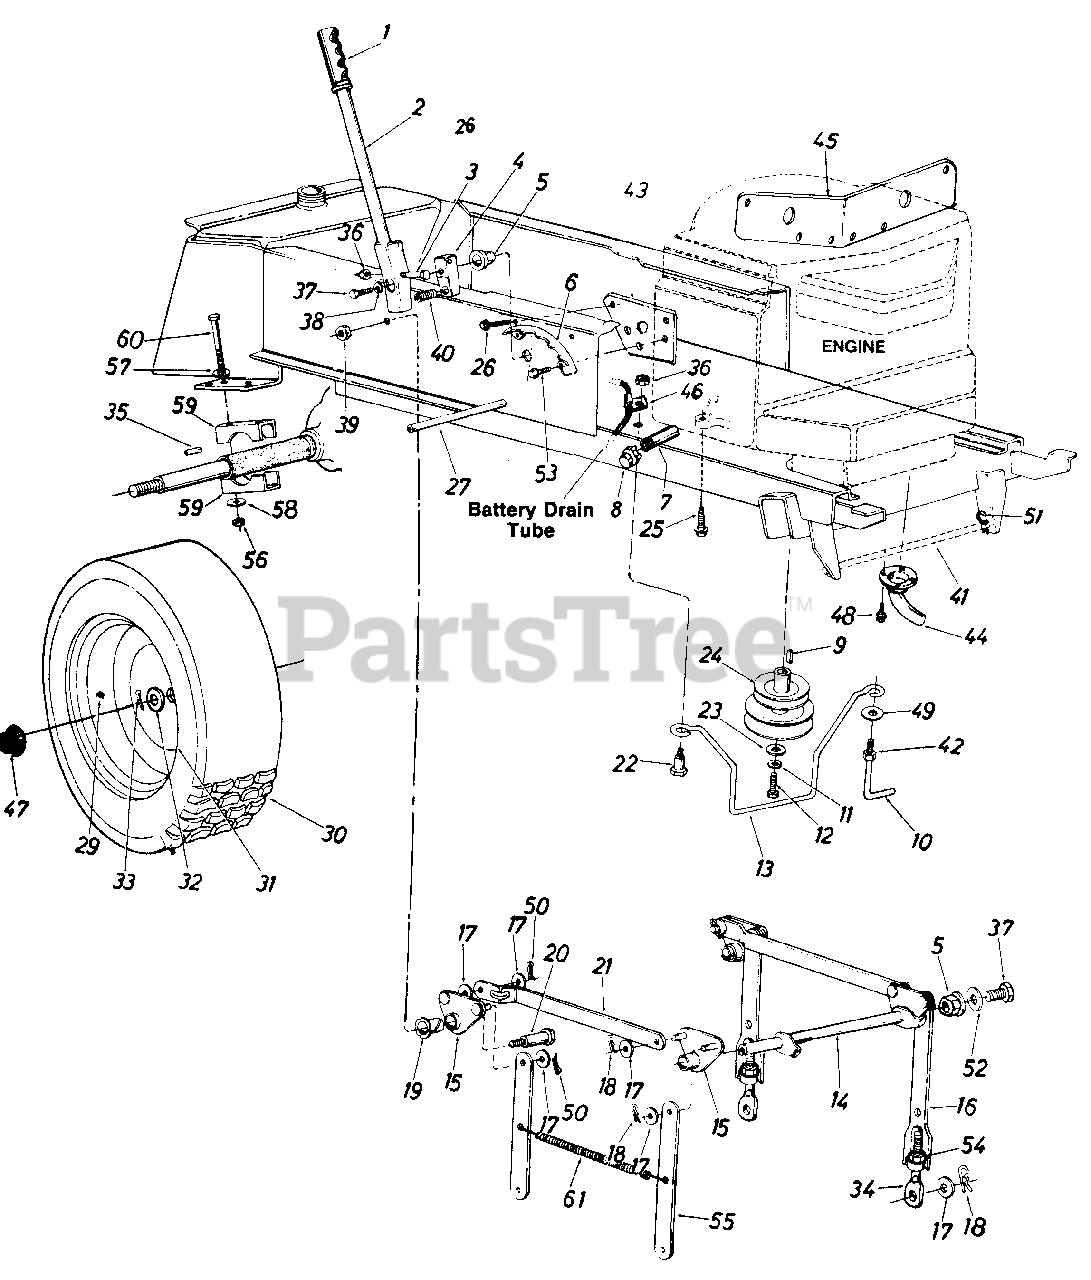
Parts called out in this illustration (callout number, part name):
1	Grip
2	Lift Handle Ass'y.
3	Hex Scr. 5/16-18 x 1.50" Lg.
4	Lift Shaft Drive
5	Plastic Hex Brg. 5/8" I.D.
8	Pipe Cap 3/8-18 Npt.
9	Sq. Key 1/4" x 1/4" x 1.50" Lg.
10	Belt Guard Lock Pin
11	L-Wash. 7/16" Scr.
12	Hex Scr. 7/16-20 x 1.50" Lg.
13	Belt Guard
14	Lift Shaft Ass'y.
15	Lift Pivot Brkt. Ass'y.
16	Adj. Deck Lift Link
17	Fl-Wash. 1/2" I.D. x 1.00" O.D. x .090
18	Hairpin Coter
19	Nyliner 5/8" I.D. x .88" Lg.
20	Shld. Scr. 5/8" Dia. x .96" Lg. 3/8-16
23	Flat Wash. .44" I.D. x 1.25" O.D. x .17
24	Two-Step Engine Pulley 4.75" & 5.56
25	Hex Wash. Hd. Scr. 3/8-16 x 1.25" Lg.
26	Hex Thd. Rolling Scr. 5/16-24 x .50" Lg.
27	Running Board Rod
29	Air Valve
30	Rear Wheel Ass'y. Comp.
33	Coter Pin 3/16" Dia. x 1.50" Lg.
34	Eye Bolt Adj. Link 1/2-13 Thd.
35	Sq. Key 1/4 x 3.0"
36	Hex Cent. L-Nut 5/16-18 Thd.
37	Hex Scr. 5/16-24 x .62" Lg.
38	L-Wash. 5/16" Scr.
39	Hex Top L-Nut 3/8-1fi Thd.
40	Compression Spriny
41	Deck Connecting Rod
42	Hex Nut 5/16-24 Thd.
43	Index Brkt. Reinforcement Plate
44	Exhaust Pipe
45	Heat Shield
46	Mounting Clamp
47	Hub Cap
48	Hex Wash. Hd. AB-Tap Scr. #10 x .50" Lg.
49	Belle-Wash. 39" l.D.
50	Coter Pin .09 Dia. x 1.0" Lg.
51	Int. Coter Pin
52	Flat Wash. .34" I.D. x 1.12" O.D. x .125
53	Hex Wash. Hd. AB-Tap Scr. 5/1 6 x .62" Lg.
54	Hex Nut 1/2-13 Thd.
56	Hex Nut 3/8-16 Thd.
57	Fl-Wash. .385" I.D. x .87" O.D.
58	Bell-Wash. .39" I.D. x 1.13" O.D.
59	Rear Axle Bracket
60	Hex Bolt 3/8-16 x 3.5" Lg.
61	Extension Spring 8.25" Lg.
